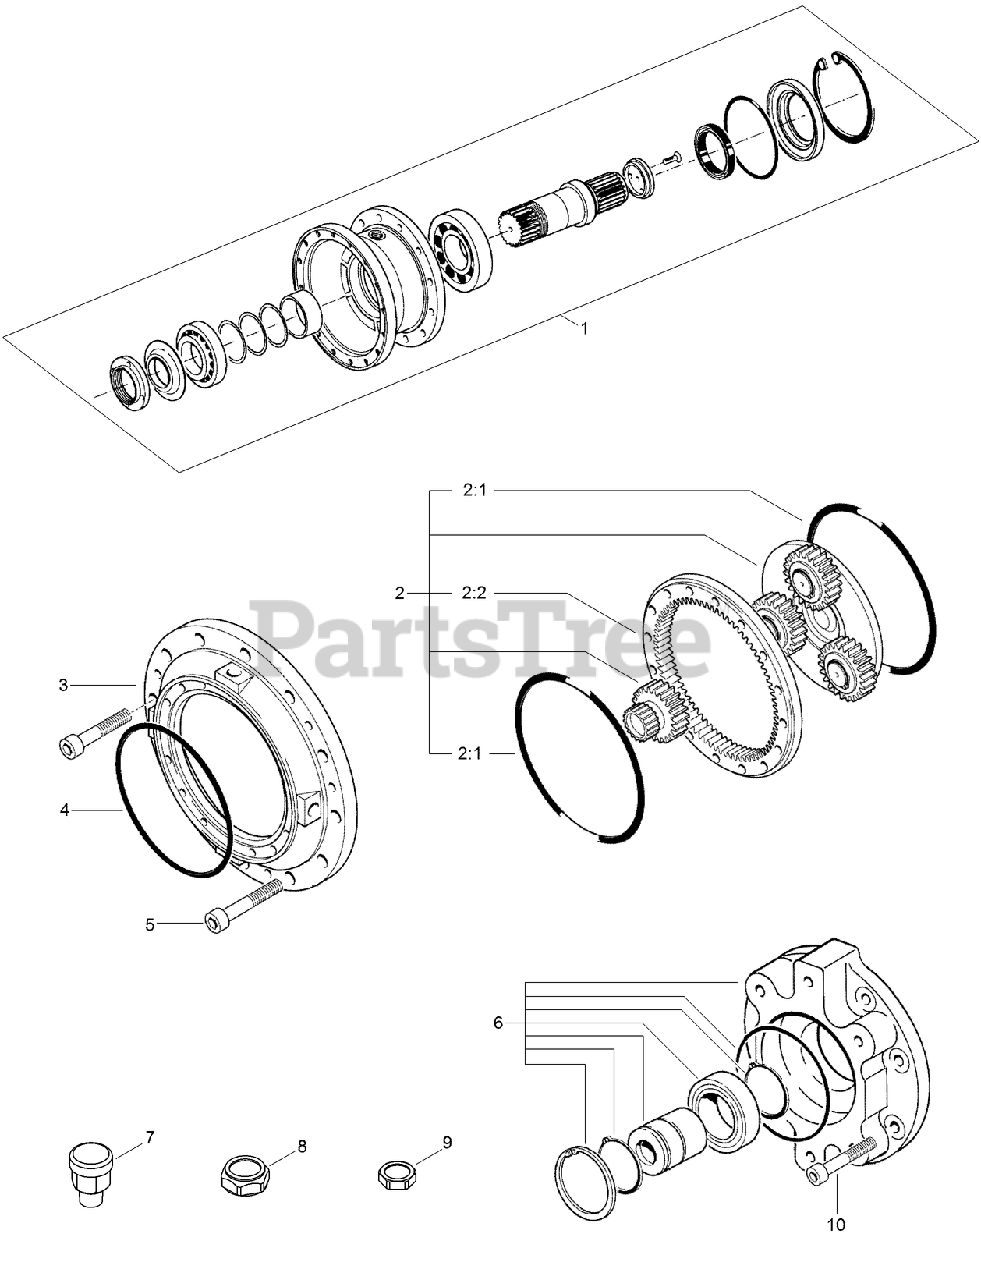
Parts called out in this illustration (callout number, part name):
1	OUTPUT KIT
2	REDUCTION STAGE KIT
2:1	O-RING
2:2	RING-TOOTHED
3	COVER-CONNECTION
4	O-RING
6	MOTOR ADAPTER KIT
7	PLUG-BREATHER
8	PLUG-LEVEL
9	PLUG-MAGNETIC
